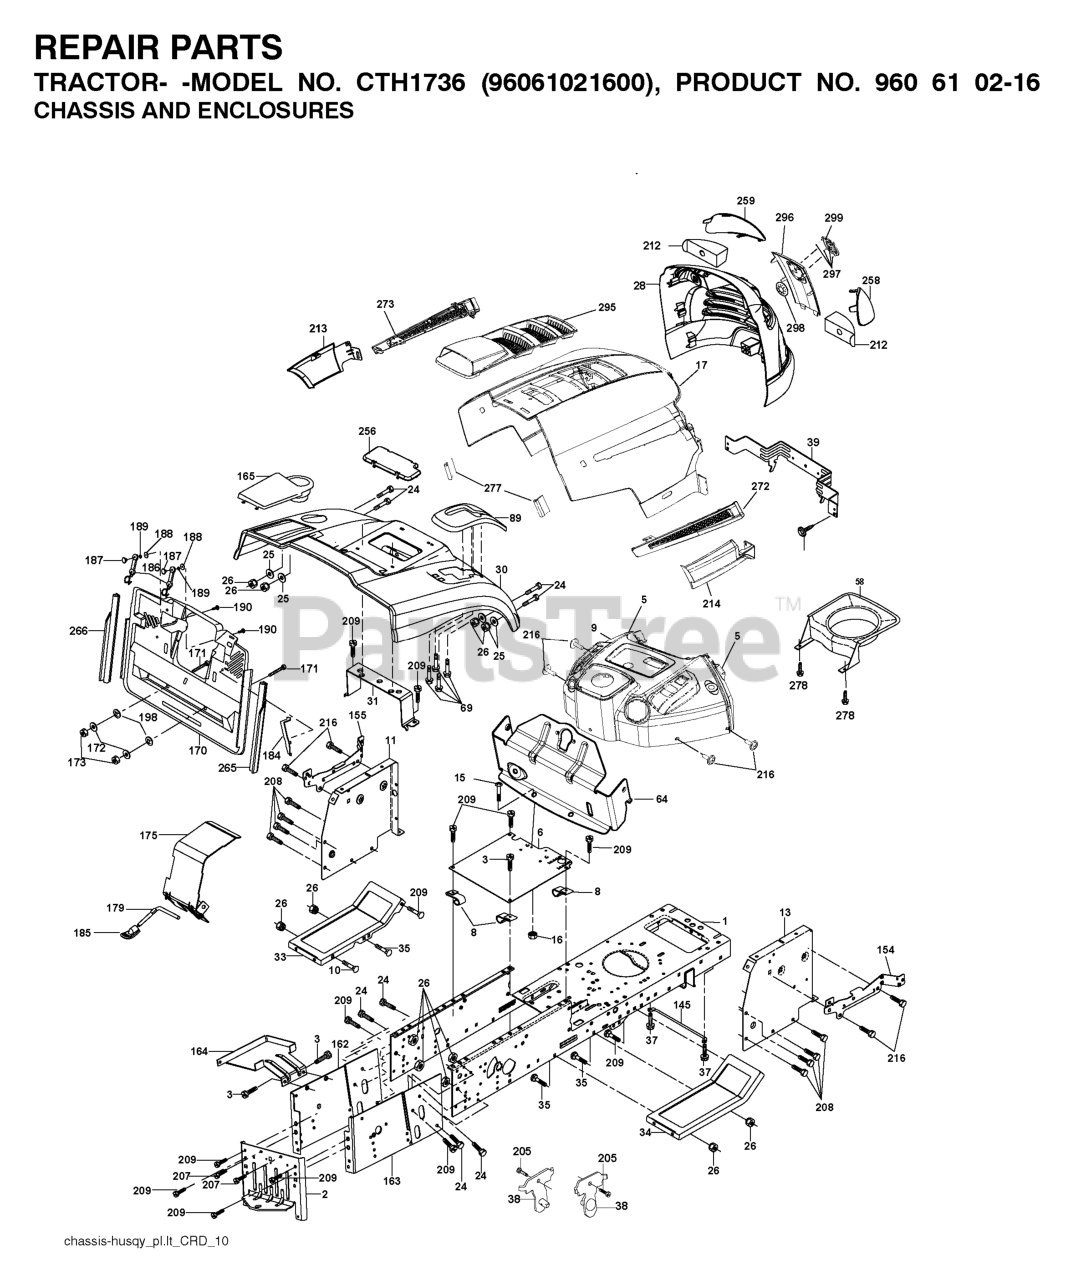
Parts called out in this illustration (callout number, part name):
2	DRAWBAR
3	SCREW 3/8-16X3/4
5	BUMPER.HOOD.TEX.HUSQVARNA
6	PLATE
8	CLIP,INSULATOR
10	BOLT D
11	PANEL.DASH.LH.LTX
13	PANEL ASM, DASH RH
15	Screw, Machine, Truss Head 5/16-18 UNC x 3/4
16	NUT
17	HOOD
25	WASHER
26	NUT
28	RP GRILLE/LENS ASM.
30	CONSOLE.CRD.AUTO.GRY
31	BRACKET SUPPORT FENDER
33	FOOTREST PNT LH
34	FOOTREST PNT RH
37	Screw 5/16-18 x 1/2 Hex, Self Tapping 5/16-18 x 1/2
38	BRACKET ASM PIVOT MOWER REAR
39	BRACKET PIVOT
69	SCREW.HI-LO.CONSOLE
89	CONSOLE.CRD.AUTO.GREY.2005
145	ROD.PIVOT.HOOD
162	BRACKET
163	BRACKET EXTEN CHASSIS RH CRD
165	RP.COVER.BATTERY.CRD.GREY
172	WASHER
175	DOOR TRAP
179	ROD PIVOT FBI
184	BRACKET.ACTUATOR.BAGGER.SRD
186	LATCH ASSY
187	WELDNUT
189	LOCKWASHER #10
190	SCREW
207	SCREW, 5/16-18 X 1/2
208	SCREW 3/8-16X1/2
209	SCREW, 3/8-16X3/4
212	INSERT REFLECTIVE
213	SKIRT SIDE LH
214	SKIRT SIDE RH
216	SCREW HEXWSHR 1/4-20X3/4
256	COVER FENDER CRD
258	LENS.HUSQVARNA LT.RH
259	LENS.HUSQVARNA LT.LH
265	SEALING
266	SEALING
272	VENT SIDE HOOD LH
273	VENT SIDE HOOD RH
277	BUMPER DASH
278	SCREW
295	VENT TOP HOOD
296	TRIM
297	CLIP.RETAINER.TINNER.
298	NUT PUSH M
299	RP LOGO
